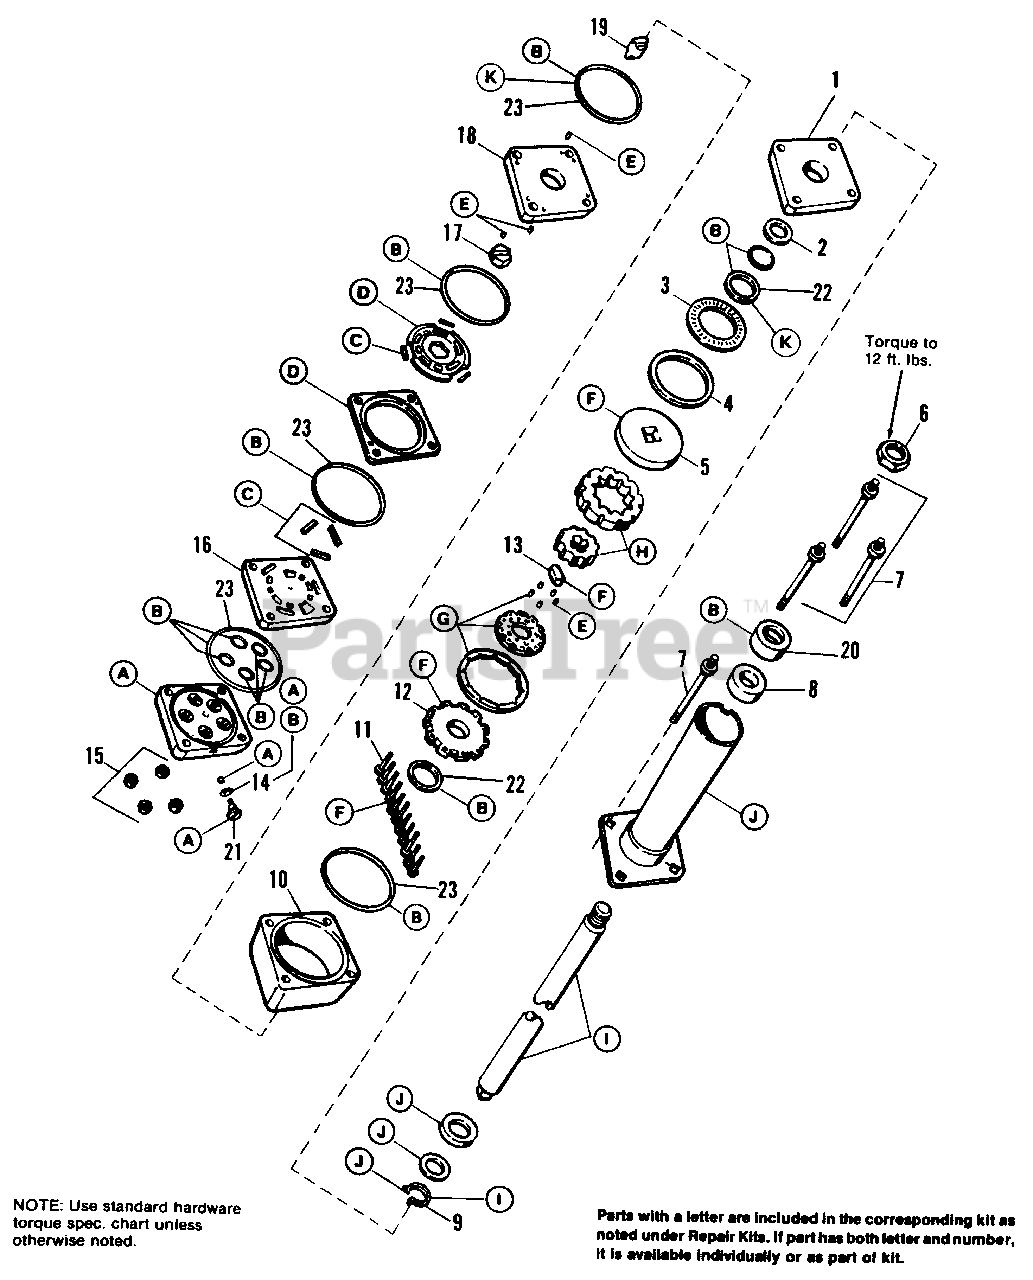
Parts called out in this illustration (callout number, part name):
1	PLATE, UpperCover
2	SPACER, Seal
3	BEARING, Thrust
5	PLATE, Drive
6	NUT, Hex, 5/8-18
7	BOLT, Special
9	RING, Retaining
10	RING, Metering
11	CAPSCREW, Hex Hd.
12	COVER, Commutator
14	"O" RING
15	LOCKNUT, Hex, 5/16-24
16	MANIFOLD, Port
17	DRIVE ASSY., Hex
18	MANIFOLD, Isolation
19	LINK, Drive
22	SEAL, (1 ea. in Kit K)
23	SEAL, (1 ea. in Kit K)
A	PORT COVER & CHECK VALVE ASSY.
B	SEAL KIT
C	SPRING KIT
D	VALVE & RING KIT
E	NEEDLE ROLLER KIT
F	METERING ASSY. KIT
G	COMM. & RING ASSY. KIT
H	ROTOR ASSY. KIT
I	INPUT SHAFT ASSY. KIT
J	UPPER COVER ASSY. KIT
K	SEAL KIT (Contains Qty. 1 of Ref. No. 22 and Qty. 1 of Ref No. 23)
